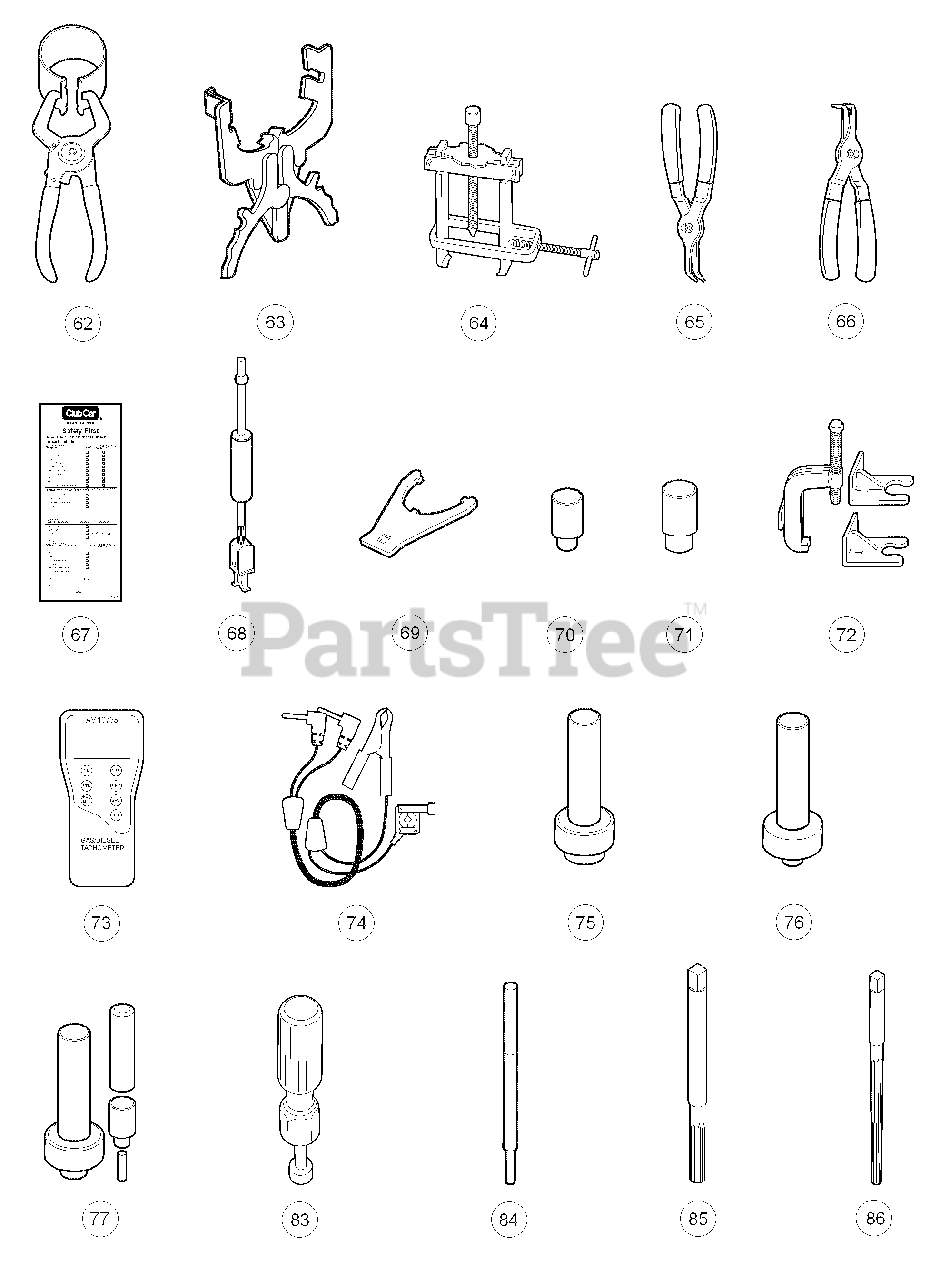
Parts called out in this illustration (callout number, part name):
62	Piston Ring Compressor Kit
63	Piston Ring Pliers
64	Puller, Special Use
65	Retaining Ring Pliers, 45° External
66	Retaining Ring Pliers, 90° Internal
67	Safety First Card
68	Seal Puller
69	Spanner Wrench
70	Steering Column Bearing Press Tool
71	Steering Column Retaining Ring Tool
72	Steering Wheel Puller Tool
73	Tachometer
74	Tachometer Diesel Probe
75	Transaxle Axle Seal Tool
76	Transaxle Pinion Seal Tool
77	Transmission Tool Kit
82	Valve Clearance Adjuster Screw Holder
83	Valve Guide Driver
84	Valve Guide Reamer
85	Valve Guide Reamer, 6.6 mm
